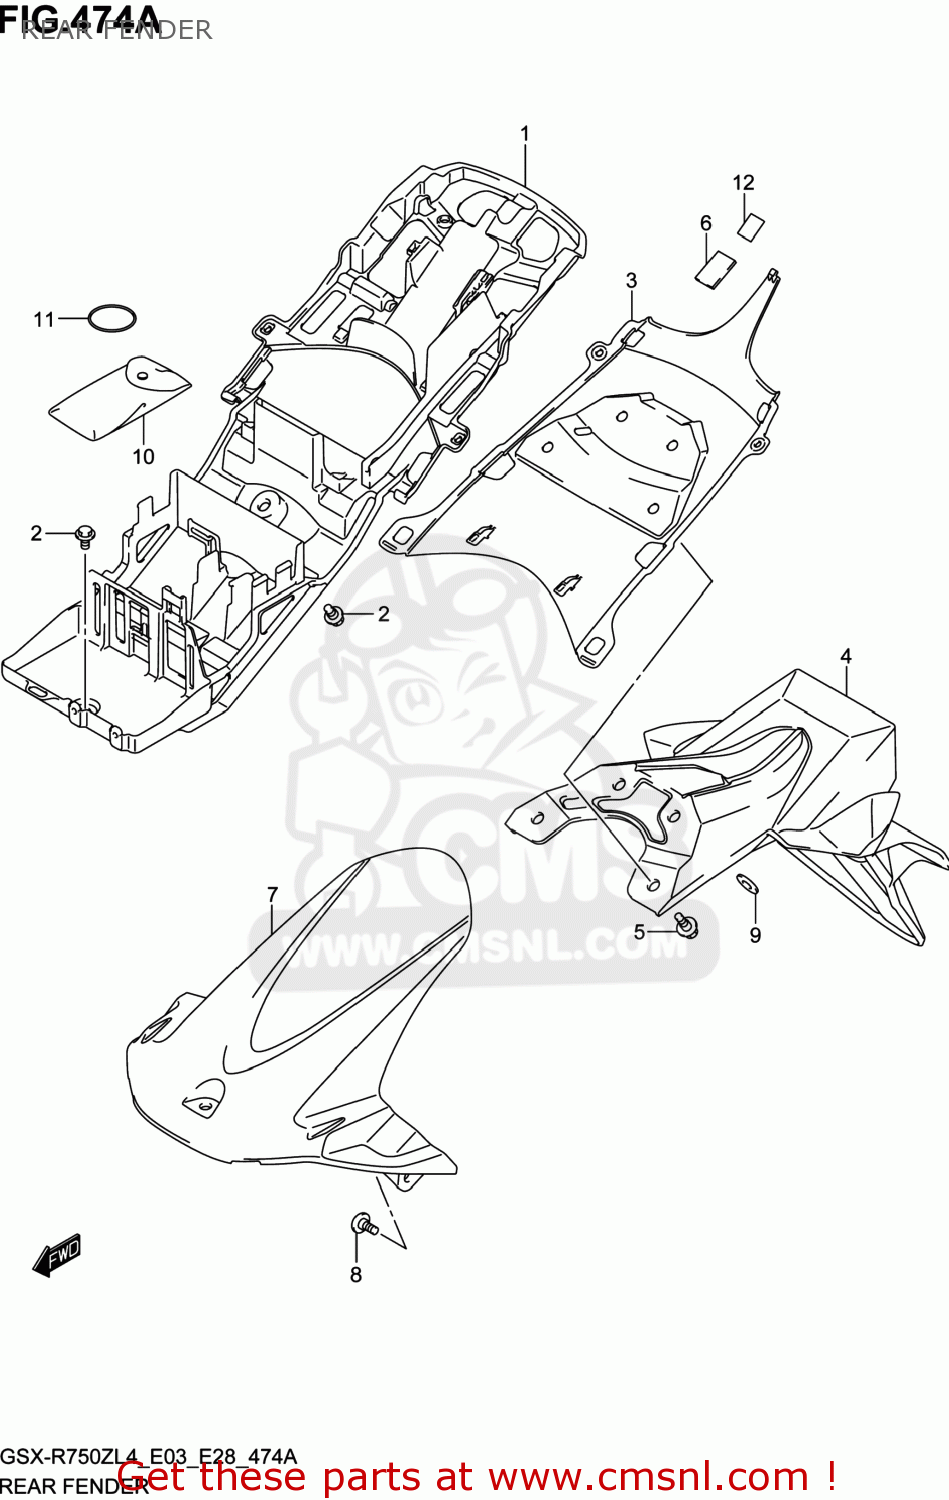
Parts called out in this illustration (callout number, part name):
1	FENDER,RR FR
2	BOLT(6X12)
3	COVER,RR FENDER FR
4	FENDER,RR RR
5	BOLT(6X17.8)
6	CUSHION,FUEL TANK ATTACHMENT
7	FENDER,RR LWR
8	SCREW(6X16)
9	WASHER(6.5X20X1.2)
10	TOOL ASSY
11	O RING(D:3.5,ID:56.5)
12	FASTENER,COWLING
